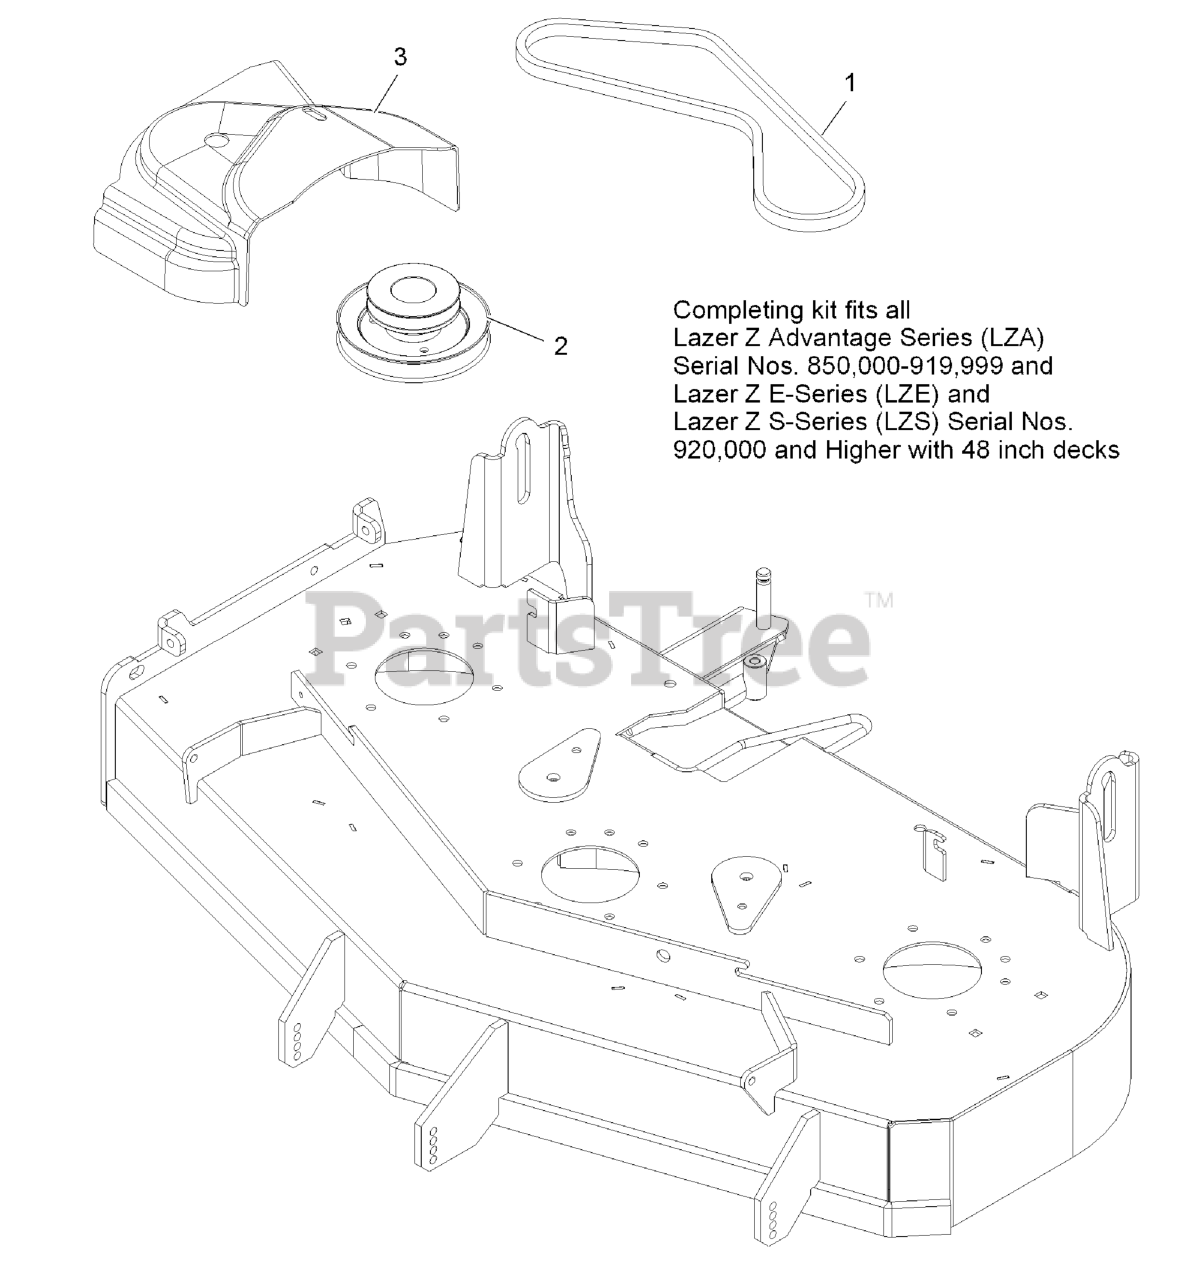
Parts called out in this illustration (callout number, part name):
1	BELT-BLOWER
2	JACKSHAFT-UV DRIVE, 484 S
3	COVER,BELT UV 48
